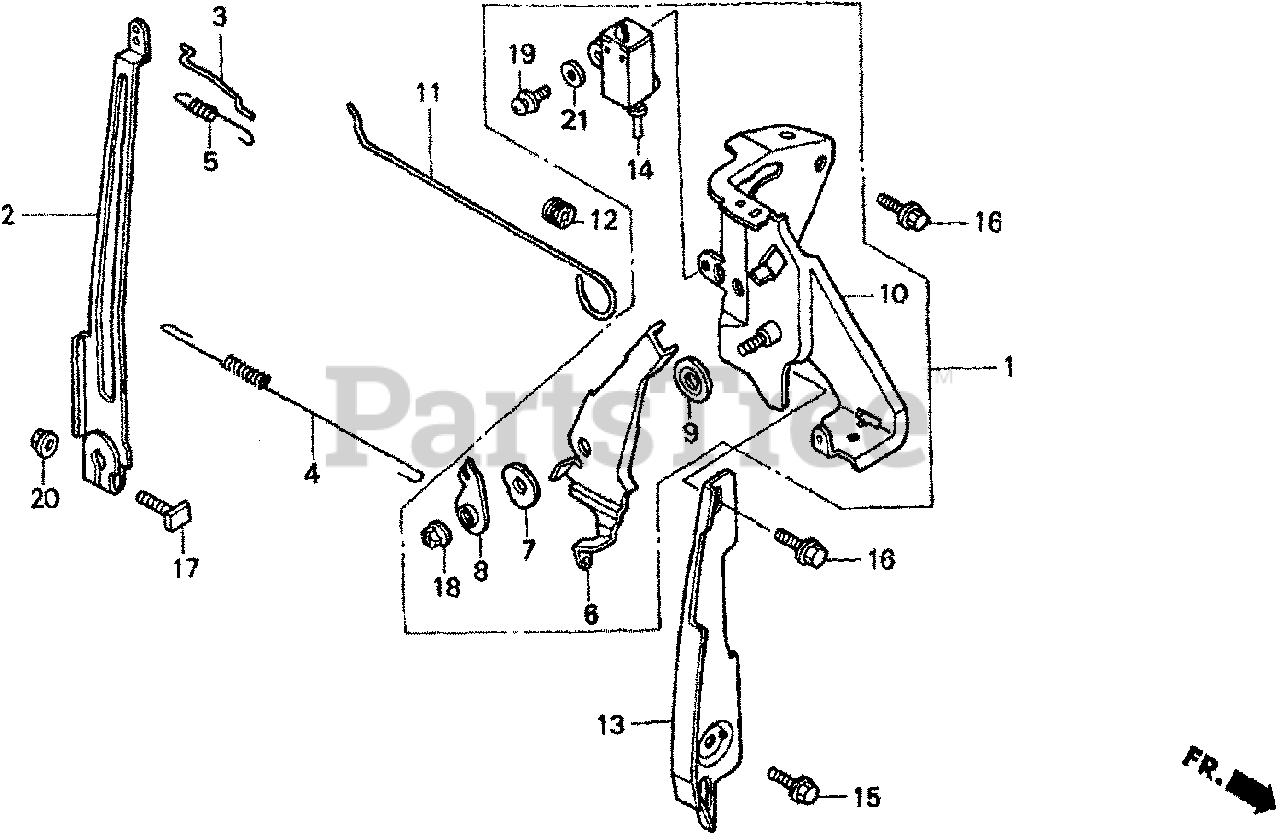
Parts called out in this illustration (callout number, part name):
1	CONTROL ASSY.
2	ARM, GOVERNOR
3	ROD, GOVERNOR
4	SPRING, GOVERNOR
5	SPRING, THROTTLE RETURN
6	LEVER, CONTROL
7	SPRING, LEVER
8	WASHER, CONTROL LEVER
9	SPACER, CONTROL LEVER
10	BASE, CONTROL
11	ROD, CHOKE CONTROL
12	GROMMET, CHOKE ROD
13	PLATE, SIDE
14	SWITCH ASSY., ENGINE STOP (N.O)
15	BOLT, FLANGE (6X12) (CT200)
16	BOLT, FLANGE (6X14)
17	BOLT, GOVERNOR ARM
18	NUT, SELF-LOCK (6MM)
19	SCREW-WASHER (4X12)
20	NUT, FLANGE (6MM)
21	WASHER, PLAIN (4MM)
